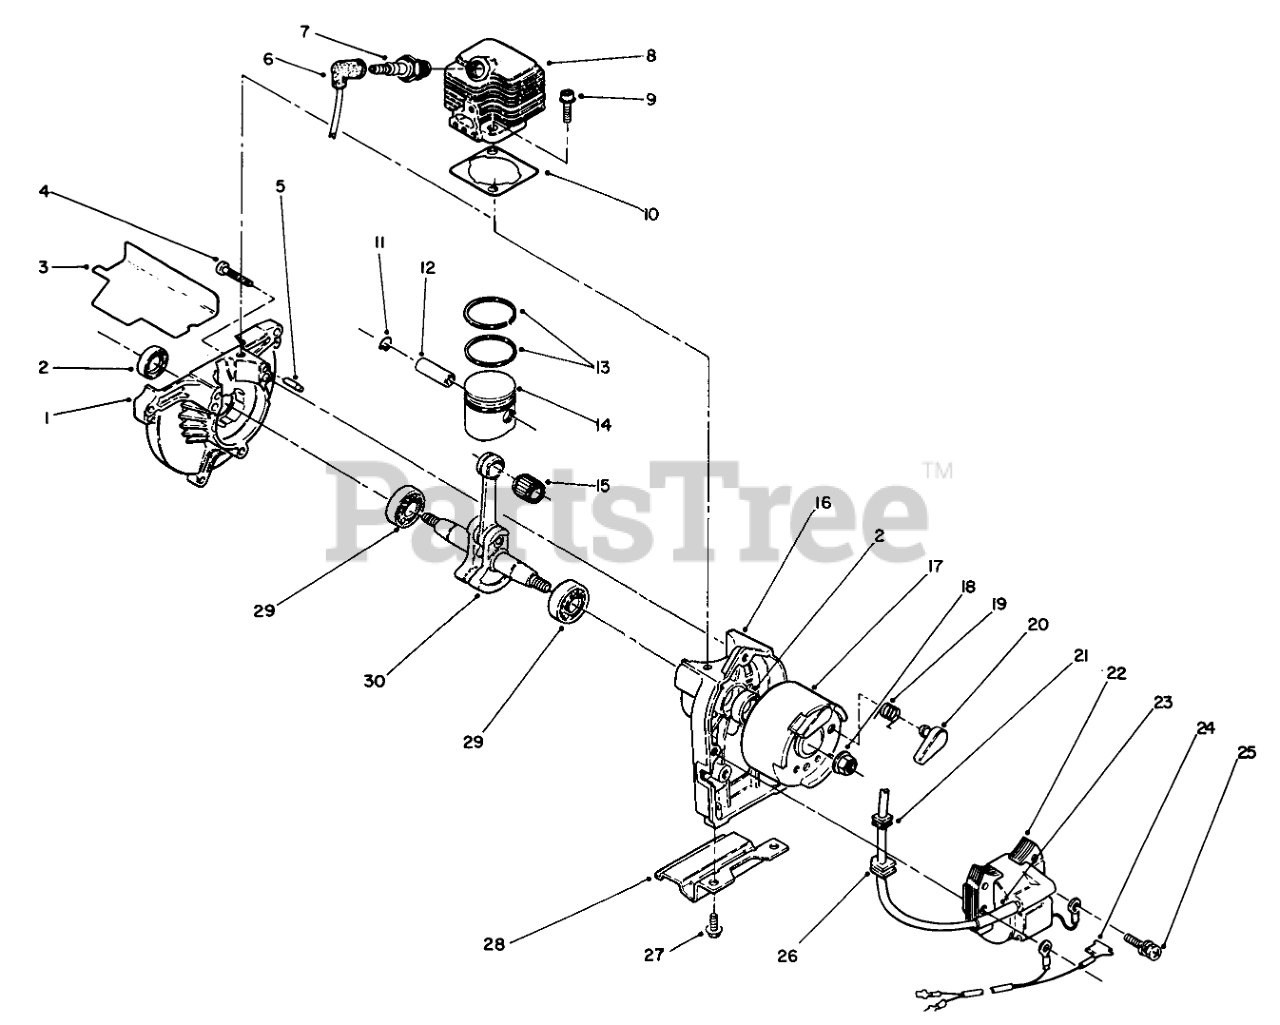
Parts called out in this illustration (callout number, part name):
1	DRIVE CASE
2	OIL SEAL
3	BAFFLE GASKET
4	Screw
6	PLUG BOOT
7	Plug-Spark
8	CYCLINDER
10	Gasket-Cylinder Head
11	CLIP, PISTON PIN
12	PIN, PISTON
13	RING,PISTON
14	Piston Assembly (Incl. Ref. #12)
15	BEARING, NEEDLE
16	STARTER CASE
17	Flywheel Assembly (Incl. Ref. #19 & 20)
19	RETURN SPRING
20	RATCHET
21	GROMMET
22	IGNITION COIL
24	LEAD WIRE
25	BOLT AND WASHER
26	GROMMET
27	SCREW & WASHER
28	STAND
29	BEARING
30	Crankshaft Assembly
